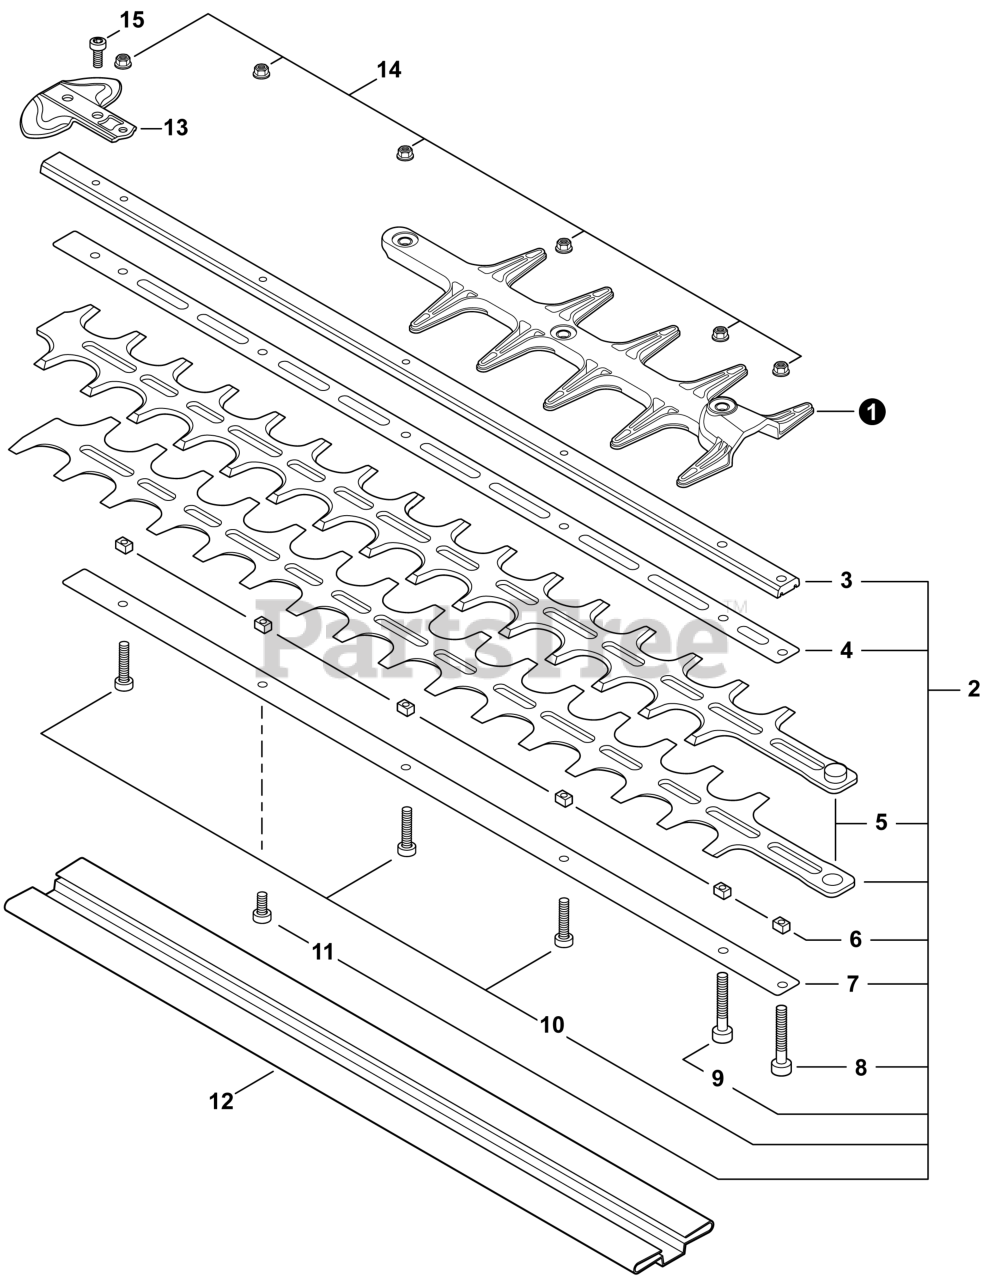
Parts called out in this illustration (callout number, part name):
1	GUARD, CUTTER BLADE
2	CUTTER ASSY, 20"
3	SUPPORT, CUTTER 20"
4	PLATE, CUTTER 20"
5	CUTTER, 20"
6	GUIDE, BLADE 5
7	PLATE, CUTTER 20"
8	BOLT, TORX 5x30
9	BOLT, TORX 5x35
10	BOLT, TORX 5x25
11	BOLT, TORX 5x20
12	SCABBARD
13	GUARD, TIP
14	NUT, FLANGE M5
15	BOLT, TORX 5x8
